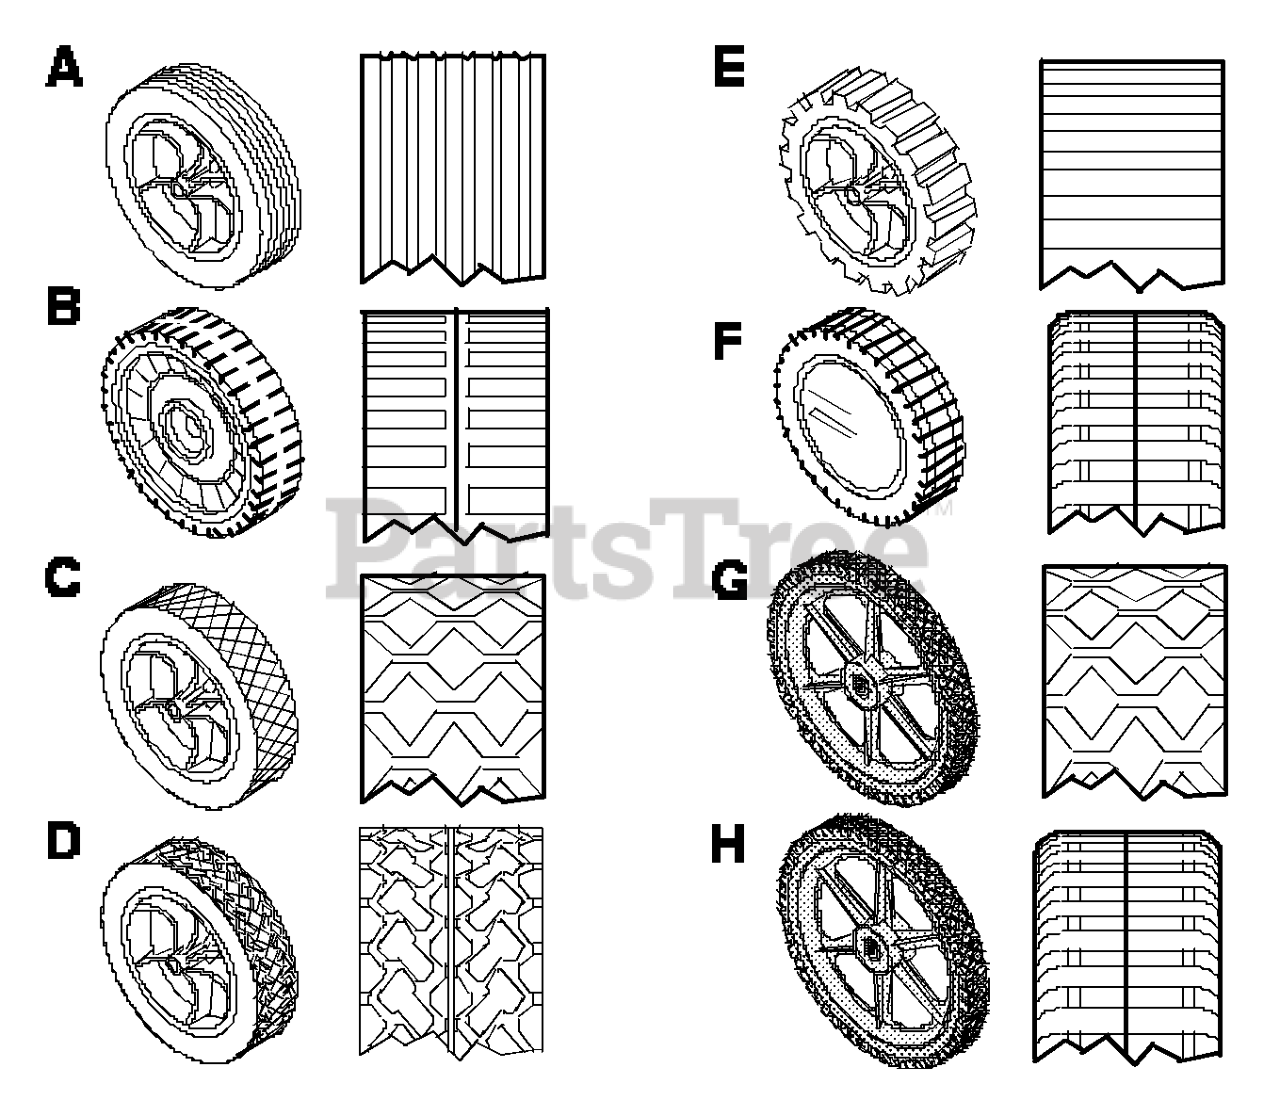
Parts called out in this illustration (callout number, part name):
C	6-inch Plastic, White
B	7-inch Plastic, White
C	7-inch Plastic, White
D	7-inch Plastic, White
B	7-inch Plastic, Light Gray
C	7-inch Plastic, Light Gray
B	7-inch Plastic, Dark Gray
C	7-inch Plastic, Dark Gray
A	WHEEL & TIRE ASSEMBLY, Light Gray, 8"
C	8-inch Plastic, White
D	WHEEL & TIRE ASSEMBLY, White, 8"
E	WHEEL & TIRE ASSEMBLY, White, 8"
F	WHEEL & TIRE ASSEMBLY, White, 8"
C	8-inch Plastic, Light Gray
D	8-inch Plastic, Light Gray
F	8-inch Plastic, Light Gray
A	8-inch Plastic, Dark Gray
C	8-inch Plastic, Dark Gray
D	8-inch Plastic, Dark Gray
E	8-inch Plastic, Dark Gray
F	8-inch Plastic, Dark Gray
A	8-inch Metal, White
C	8-inch Metal, White
E	8-inch Metal, White
F	8-inch Ball Bearing, Light Gray
F	8-inch Ball Bearing, Dark Gray
G	14-inch, White
H	14-inch, White
G	14-inch, Light Gray
H	14-inch, Light Gray
G	14-inch, Dark Gray
H	14-inch, Dark Gray
G	WHEEL & TIRE ASSEMBLY, White, 14"
H	WHEEL & TIRE ASSEMBLY, Ball Bearing, 14"
G	14-in, Ball Bearing, Light Gray
H	14-in, Ball Bearing, Light Gray
G	14-in, Ball Bearing, Dark Gray
H	14-in, Ball Bearing, Dark Gray
